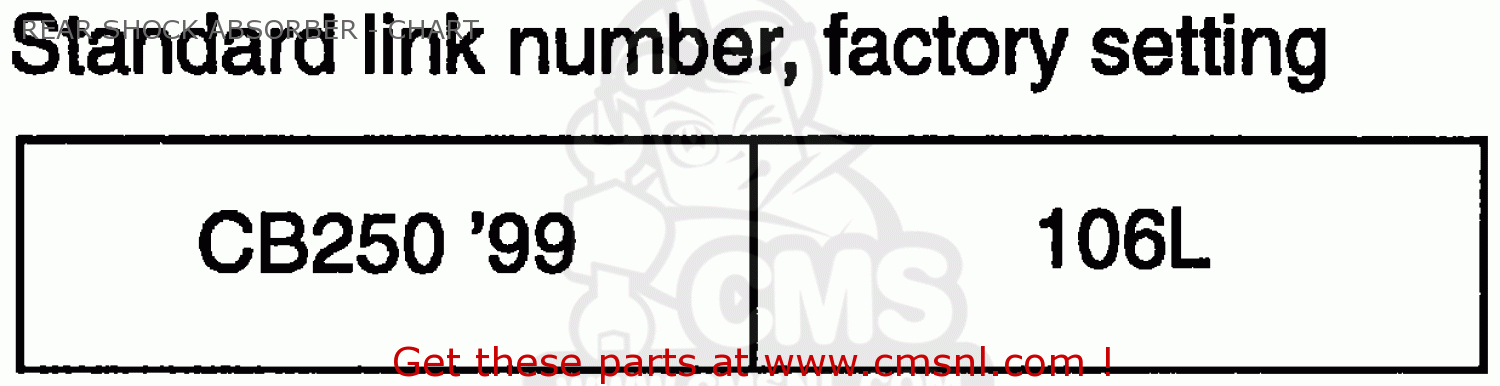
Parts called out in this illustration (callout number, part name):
1	CUSHION ASSY.,RR.
2	COLLAR, CUSHION
3	COLLAR,RR.CUSHION
4	BUSH,REAR CUSHION
6	WASHER,PLAIN,10MM
7	BOLT,FLANGE,10X35
